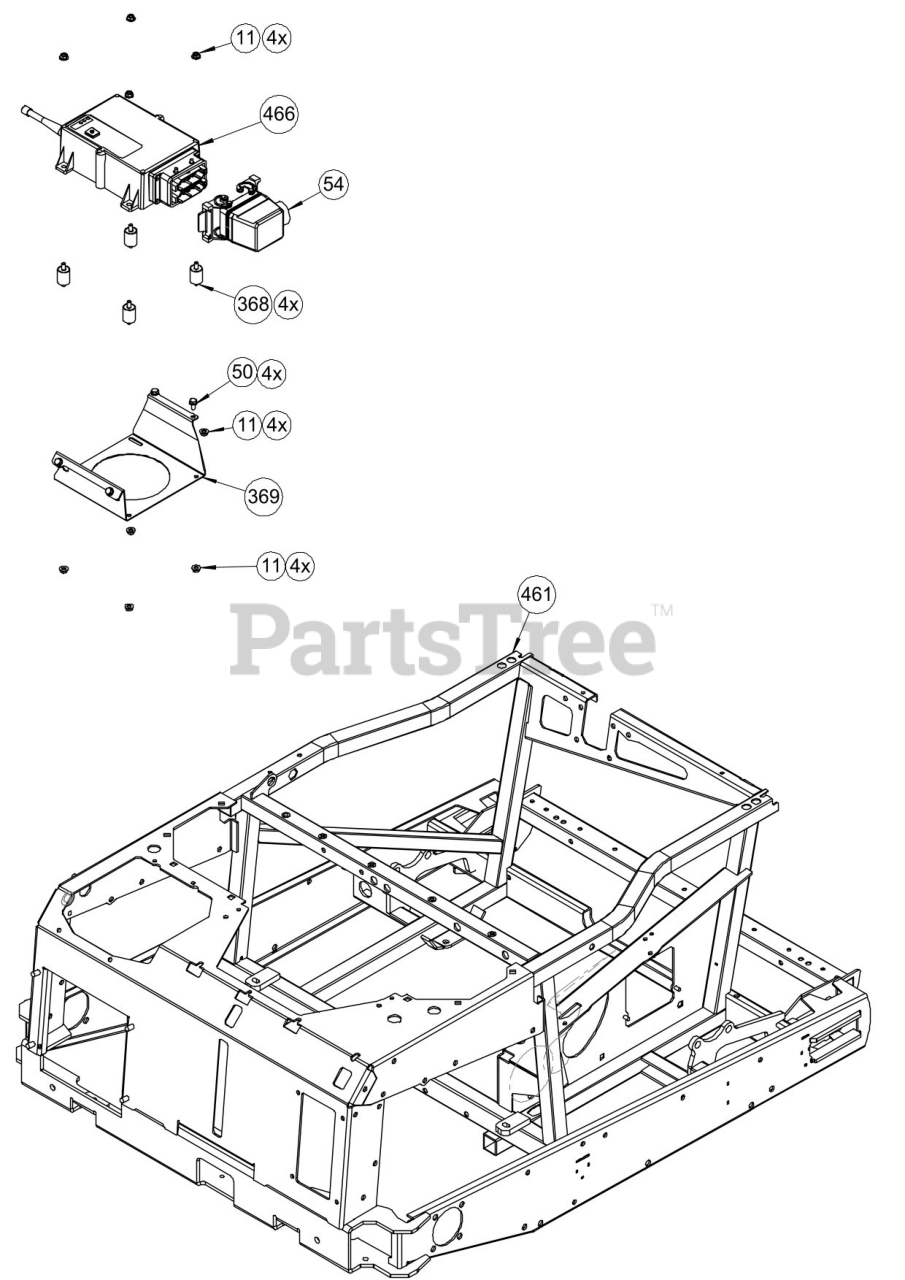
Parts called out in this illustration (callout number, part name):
11	NUT, FLG SLF LK M6 CL 8 ZCC
50	BLT, FLG SLF LK M6X12
54	HARNESS, OVIS MAIN
368	MOUNT, ISOLATOR
369	HOLDER, RC RECIEVER
461	FRAME, OVIS MAIN
466	RECIEVER, REMOTE CONTROL
